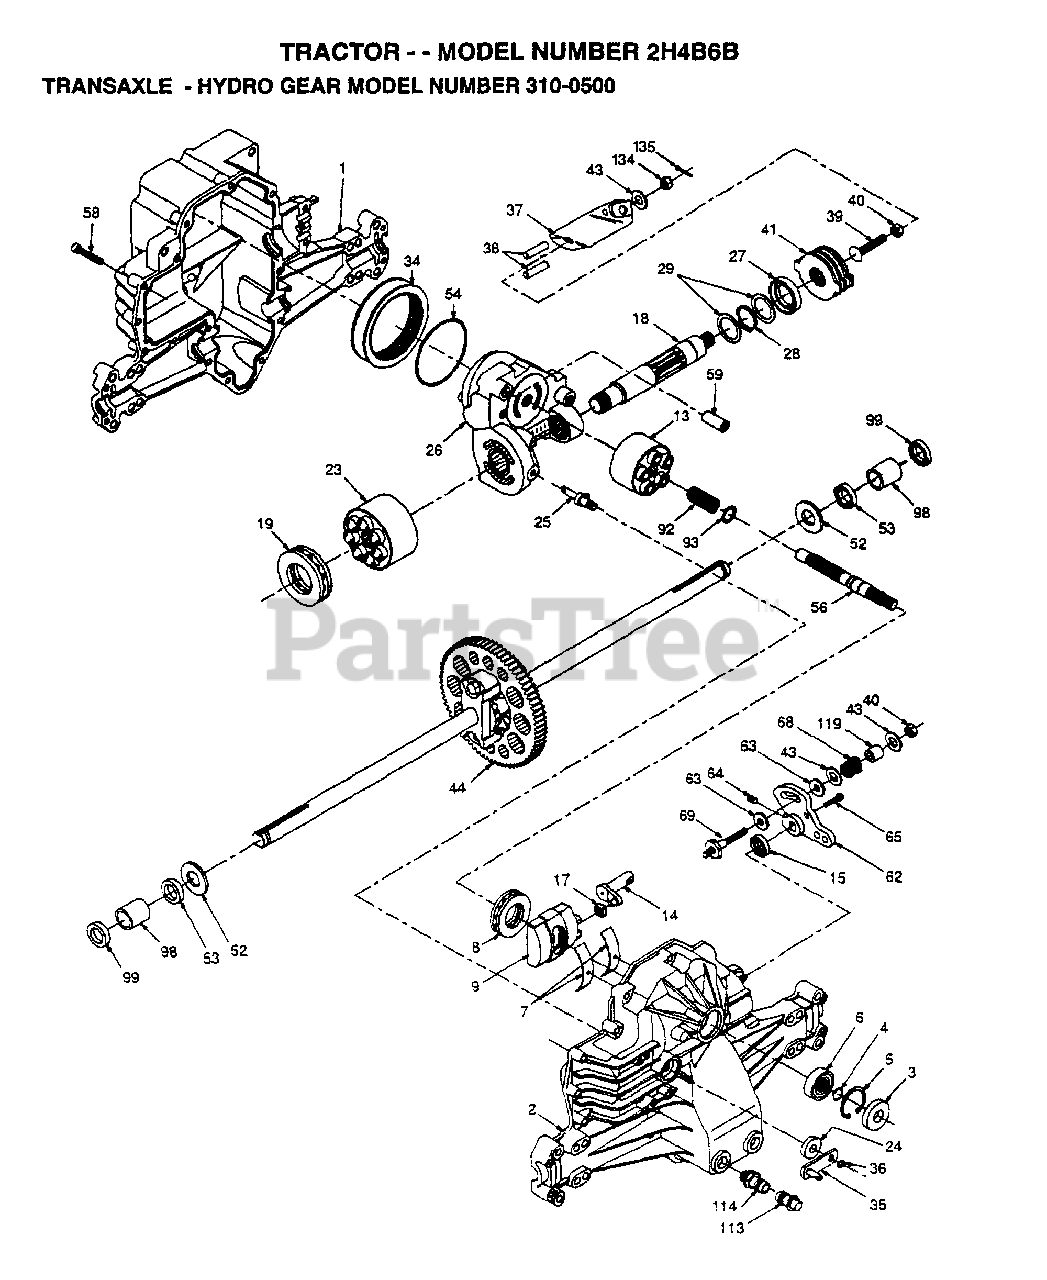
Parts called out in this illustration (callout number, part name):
1	HOUSING.L.44863RM
2	HOUSING.UPR.70122
3	SEAL.9008000-0128
4	RING.RET.2003016.
5	RING.RET.2003052.
6	BEARING.(50552)42X68X16
7	CRADLE- 2003023.
8	BEARING.2003044.
9	SWASHPLT.2003087.
13	BLOCK.CLYN.70079.
14	ARM.TRUN.2003005.
15	SEAL.9008000-0126
17	GUIDE.2000015.
18	SHAFT.HYD.2003557
19	BEARING.THS.50019
23	BLOCK.CYLIN.70082
24	SEAL.LIP.45074
25	ACTUATOR.2003555
26	KIT.CENTER.70133
27	SEAL.LIP.45075
28	RING RETAIN 50007
29	WASHER.44872
34	ELEMENT.OIL.44964
35	ARM.BYPASS.50270
36	RING.RETAIN.44870
37	ARM.ACTUAT.23710
38	PIN.ACTUAT.44891
40	NUT.LOCK.HX.50108
41	KIT.BRAKE.70135
43	WASHER HYD 44130
44	DIFFERNTIAL.70126
52	WASHER.HYD.44875
53	SEAL.HYDRO.45076
54	O RING.HYD.45077
56	SHAFT.INPUT.50005
58	BOLT.1/4-20.44876
59	PIN.HYDRO.50002
62	ARM.CONTROL.50254
63	PUCK.DAMPER.50281
64	SCREW.SET.50018.
65	BOLT #8-32 X .875
68	SPRING.HYD.50277
69	STUD.5/16-24.DANA
92	SPRING.2003014.
93	WASHER.2003017
98	BEARING.SLV.50137
99	SCREW.CAP.50154.
113	CAP.VENT.70109
114	O-RING.ASM.70110
119	SPACER.HYD.50278
134	NUT.CAS.HYD.44142
135	PIN.COT.HYD.44101
